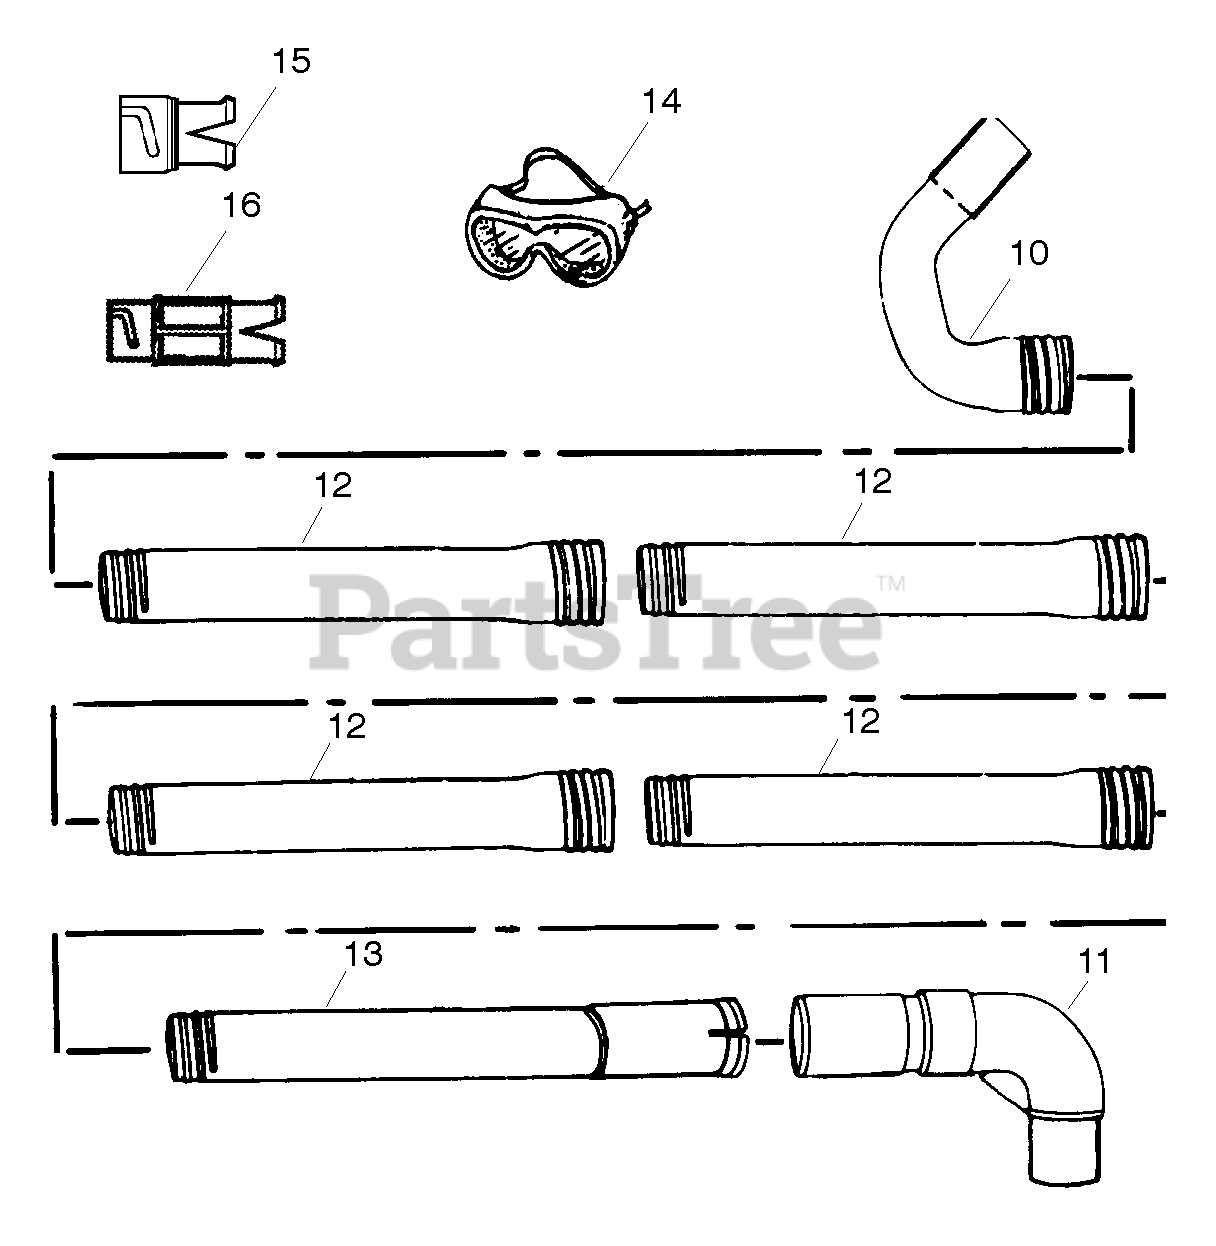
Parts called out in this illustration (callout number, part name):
12	Extension Tube
13	Pivot Tube
14	Goggles
15	Adapter
16	Adapter
